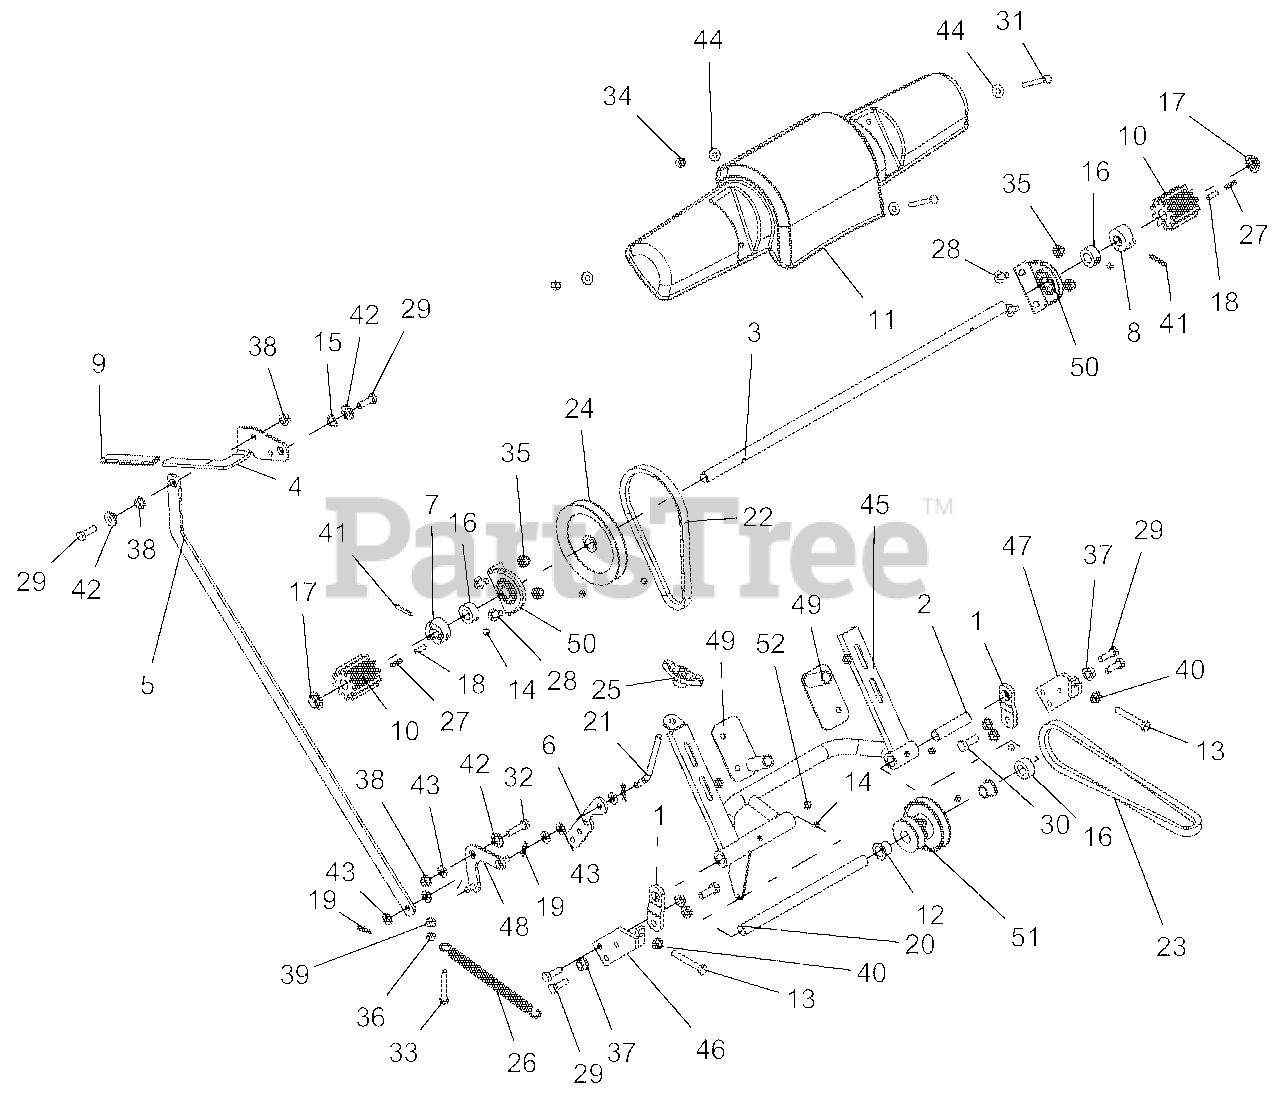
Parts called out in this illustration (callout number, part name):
1	BRKT, SP FRAME PIVOT 12331K
2	SHAFT, PIVOT, SHORT 12352K
3	SHAFT, WHEEL DRIVE 19125K
4	LEVER, SP ENGAGEMENT
5	BAR, ENGAGEMENT LEVER CONN.
6	BRKT, ENGAGE, ADJ. 20100K
7	CLUTCH, RIGHT SP -12333K
8	CLUTCH, LEFT SP -12334K
9	GRIP MZR/MOMENT SP 7/8X3/4X4
10	GEAR, DRIVE (SP) 219943K
11	COVER, PLASTIC-SP (HIGH WHEEL)
12	BUSHING,FLANGED .75X.625X.62
13	HHCS 5/16-18 X 2-1/4 FULL THD
14	SET SCREW 5/16-18 X 5/16 CP
15	WSHR-WAVE .50X.75X.015 .13FRHT
16	SET COLLAR .625ID X .50
17	NUT-PUSH .625 DIA. PAL
18	DOWEL PIN 1/4 X 3/4
19	PIN-HAIR, ENDRIES #25 YWZC
20	SHAFT, PIVOT, LONG 12351K
21	THDED ROD.31-18X3.0THD YZ
22	V-BELT, 4L-RAW EDGE
23	V-BELT, 4L-RAW EDGE
24	PULLEY 5"OD X 5/8"ID
25	KNOB,WING .31-18 UNC NYL/TALC
26	SPRING, EXTENSION
27	SPRING, DRIVE ROLLER SP
28	@BLT-RHDSSQNK .31-18X.75 G5YZ
29	@BLT-HEX .31-18X1.00 GR5 YWZC
30	@BLT-HEX .38-16X1.00 GR5 YWZC
31	@BLT-HEX .25-20X2.25 GR5 YWZC
32	@BLT-HEX .31-18X1.25 GR5 YWZC
33	@BLT-HEX .25-20X2.00 GR5 YWZC
34	@NUT-LK-NYL .250-20 YWZC
35	@NUT-LK-NYL-FLG .31-18 YWZC
36	@NUT-HEX .25-20 YWZC
37	@NUT-LK-TOP-FLG .38-16 YWZC
38	@NUT-LK-TOP-FLG .31-18 YWZC
39	@NUT-LK-TOP-FLG .25-20 YWZC
40	@NUT-SPNLK-FLG .312-18 YWZC
41	PIN-ROLL .188X1.25
42	BSHG-FLG .32X.500X.344X.880
43	@WSHR-FL-STL.344X.688X.065YWZC
44	@WSHR-FL-STL.312X.734X.065 YWZ
45	WMT-SELF PROPEL FRAME 19038K
46	WMT-PIVOT, RH SP FRAME 17367K
47	WMT-PIVOT, LH SP FRAME 17368K
48	WMT-BELL CRANK 18959K
49	WMT, SP BELT COVER MOUNTING
50	BEARING ASSY, SP TOPSHAFT, HWM
51	WMT,DBL SP IVP PULLEY 17344K
52	GREASE FITTING 5/16 DRIVE IN
